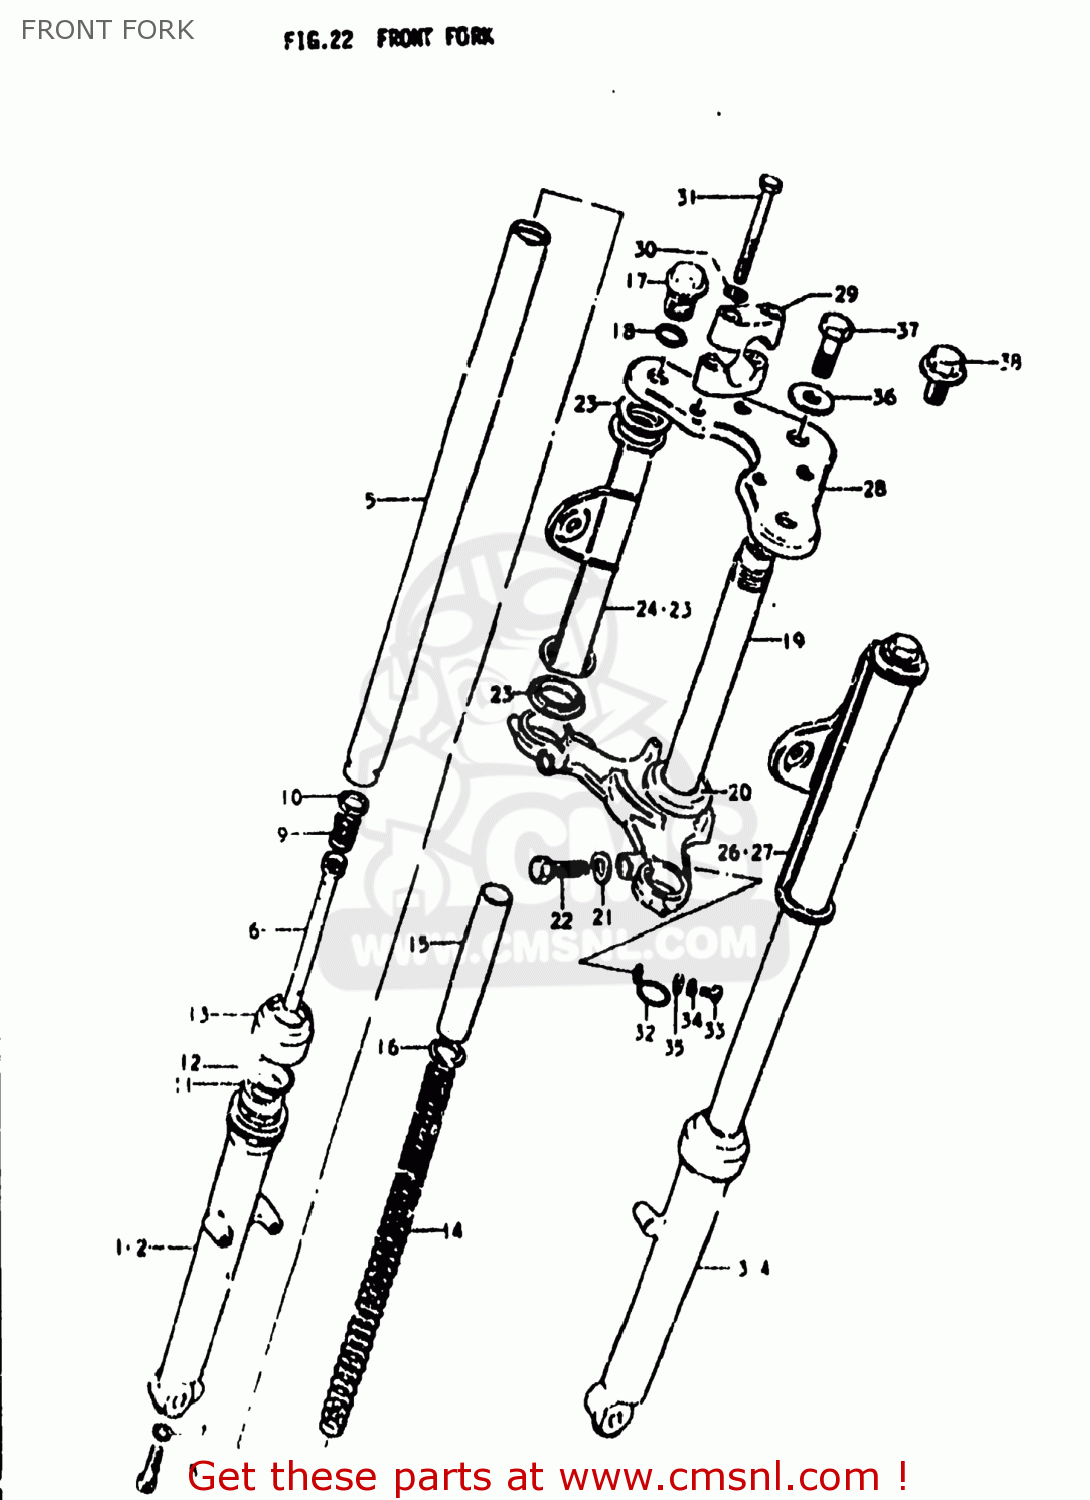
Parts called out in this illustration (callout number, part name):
0	DAMPER SET
1	TUBE,OUTER,RIGHT
2	TUBE,OUTER,RIGHT
3	TUBE,OUTER,LEFT
4	TUBE,OUTER,LEFT
5	TUBE,FORK,INNER
6	CYLINDER,FRONT FORK
7	GASKET (NAS)
8	BOLT
9	SPRING,REBOUND
10	RING,PISTON
11	OIL SEAL,FRONT FORK
12	CIRCLIP,FORK OIL SEAL
13	DUST SEAL
14	SPRING
15	SPACER,SPRING
16	JOINT,SPRING
17	CAP
18	O-RING,FORK INNER TUBE
19	STEM,STEERING
20	RACE,STEERING OUTER LWR
21	LOCK WASHER
22	BOLT 10X30
23	CUSHION
24	BRACKET,HEADLAMP,RIGHT
25	BRACKET,HEADLAMP,RIGHT
26	BRACKET,HEADLAMP,LEFT
27	BRACKET,HEADLAMP,LEFT
28	HEAD,STEERING STEM
29	HOLDER,HANDLEBAR
30	LOCK WASHER
31	BOLT 8X55
32	CLIP
33	SCREW 6X12
34	LOCK WASHER
35	WASHER
36	WASHER,STEERING STEM
37	BOLT,STEERING STEM HEAD
38	BOLT
